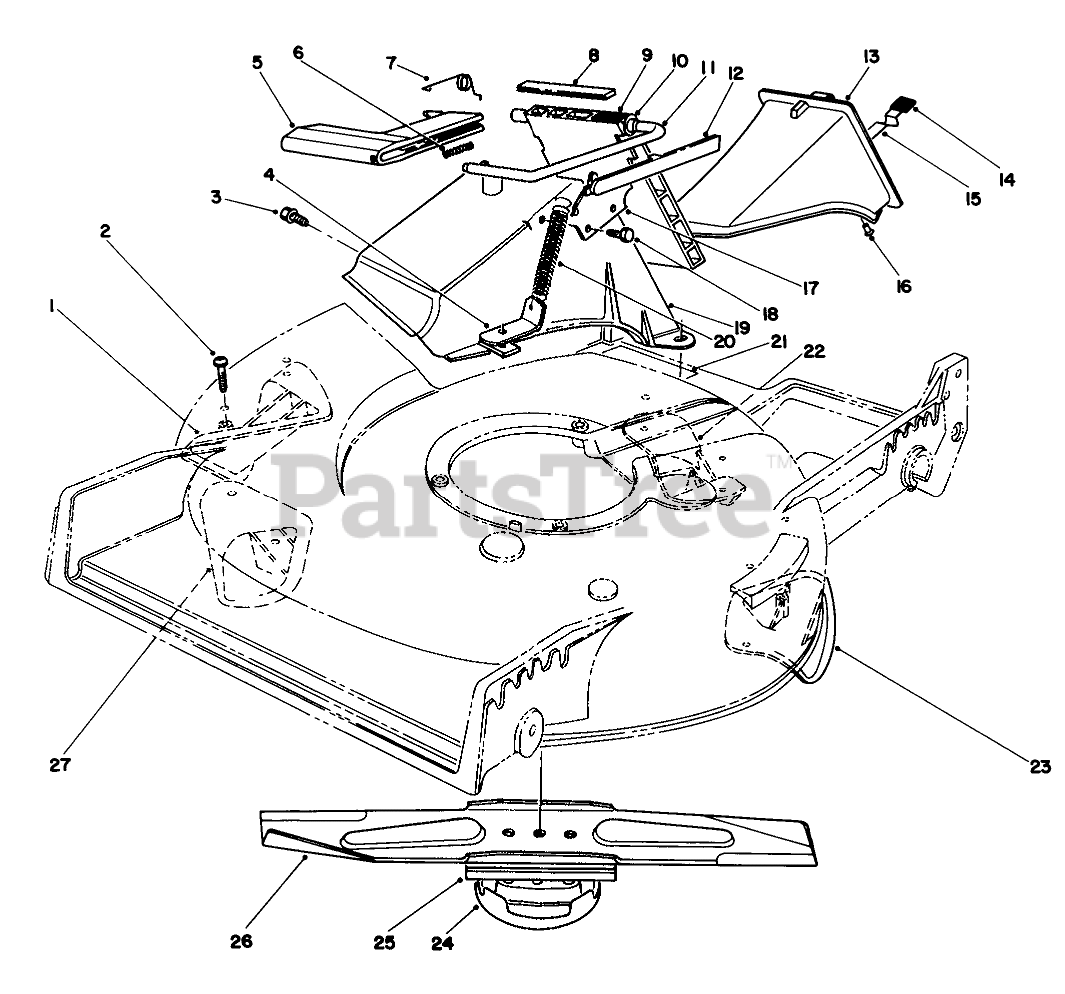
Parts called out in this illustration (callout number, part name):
1	KICKER
2	#8 X .625" PHILPS PAN H
3	SCREW AND WASHER ASM
4	Bracket-Spring
5	Handle-Door
6	Spring
7	RETAINER-DOOR
8	Cover-Door
9	Door-Discharge
10	BUSHING-NYLON
11	Rod-Door
12	Cover-Handle
13	Plug Assembly (Incl. Ref. #14-16)
14	GRIP-LATCH
15	LATCH-PLUG, DISCHARGE
16	RIVET-HEAD, FLAT
17	DOOR LATCH PLATE
18	SCREW-PLASTITE
19	DISCHARGE TUNNEL
20	SPRING-DOOR
21	DECAL
22	KICKER
23	KICKER
24	CUP-SCALP, ANTI
25	Stiffener
26	Blade Assembly (Incl. Ref. #25)
27	KICKER
